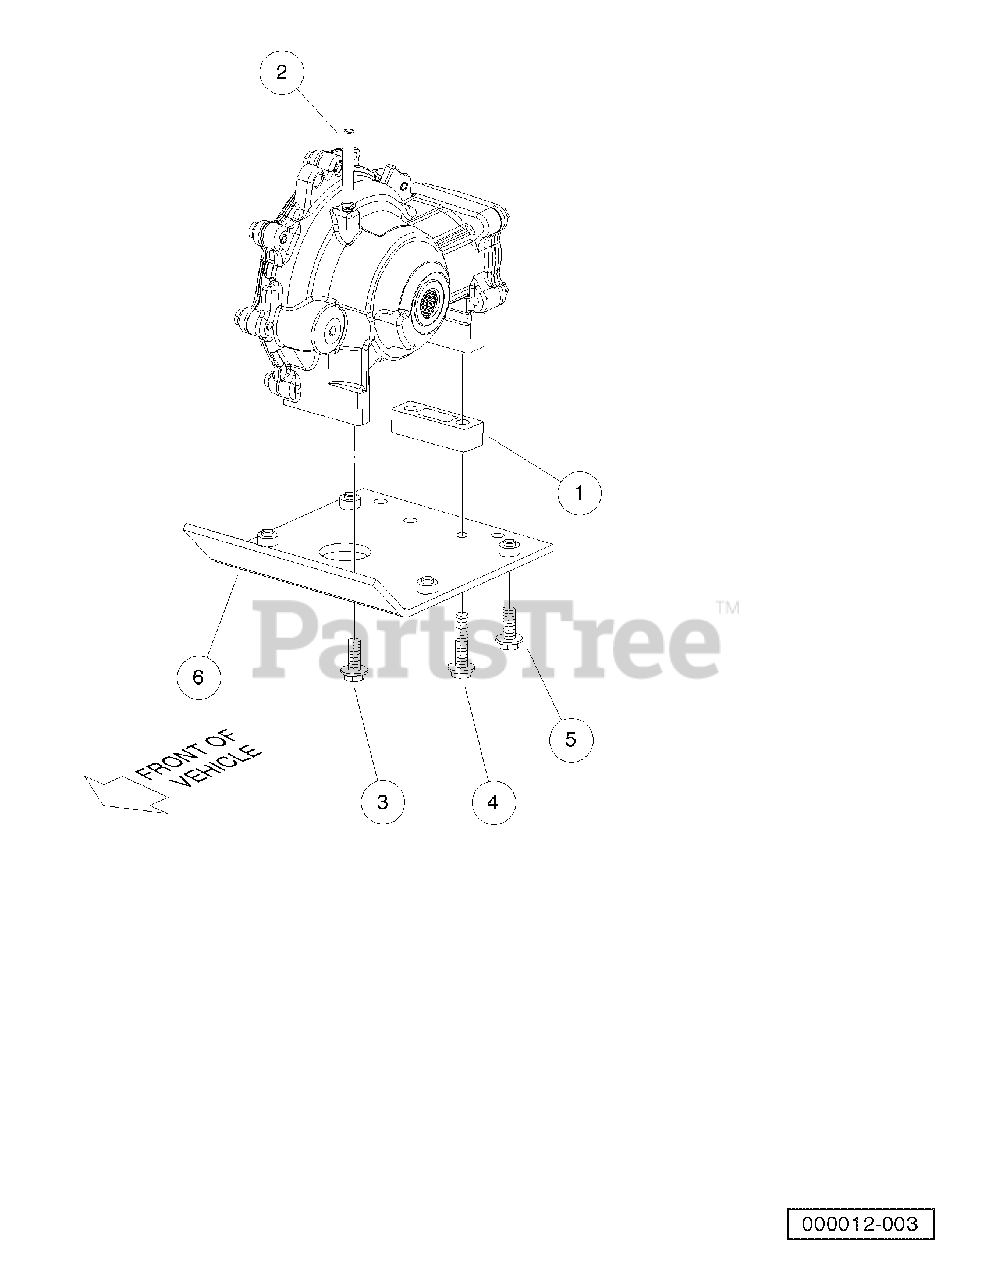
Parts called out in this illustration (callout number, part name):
1	Spacer Block, Diff
2	Hose, Vent, Front Diff
3	Bolt Flanged Head, 3/8-16x1.0 with Loctite
4	Bolt Flanged Head, 3/8-16x1.500 with Loctite
5	Bolt, Flange Head, M10 X 1.5 X 25
6	Asm, Mount, Diff Plate
